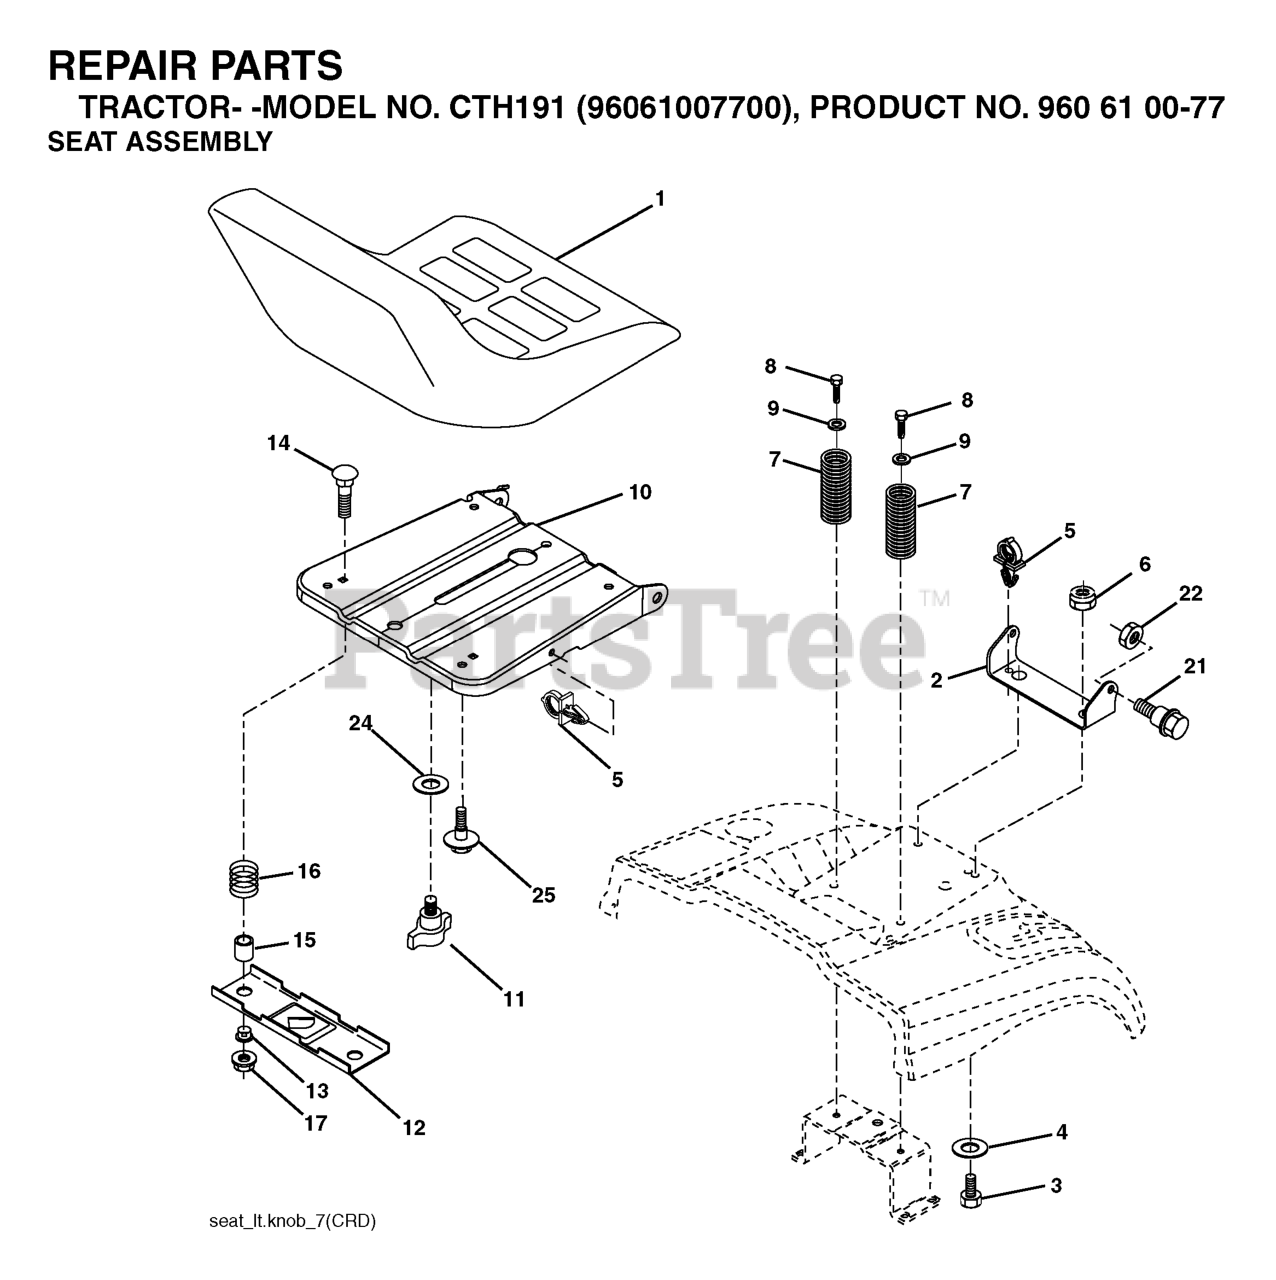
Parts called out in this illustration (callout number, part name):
1	SEAT.XG110.BLK.NO/LOGO
2	SEAT PIVOT BRKT
3	BOLT, HEX 3/8-16X1
6	NUT
7	SPRING COMPRESSION
8	SCREW 3/8-16X1
9	WASHER
10	PAN.ASM.SEAT.1SLOT
11	KNOB.SEAT.ADJ.WINGNUT
12	BRKT.MNTNG.SWITCH.SEAT.BLACK
14	BOLT.ROUND.HEAD.SQUARE.NECK
15	SPACER SPLIT
16	SPRING COMPRESSED
17	NUT T
21	BOLT.SHOULDER.5/16-18
22	NUT.71038.31-18.HEX.NYLOCK
25	BOLT,SHOULD
